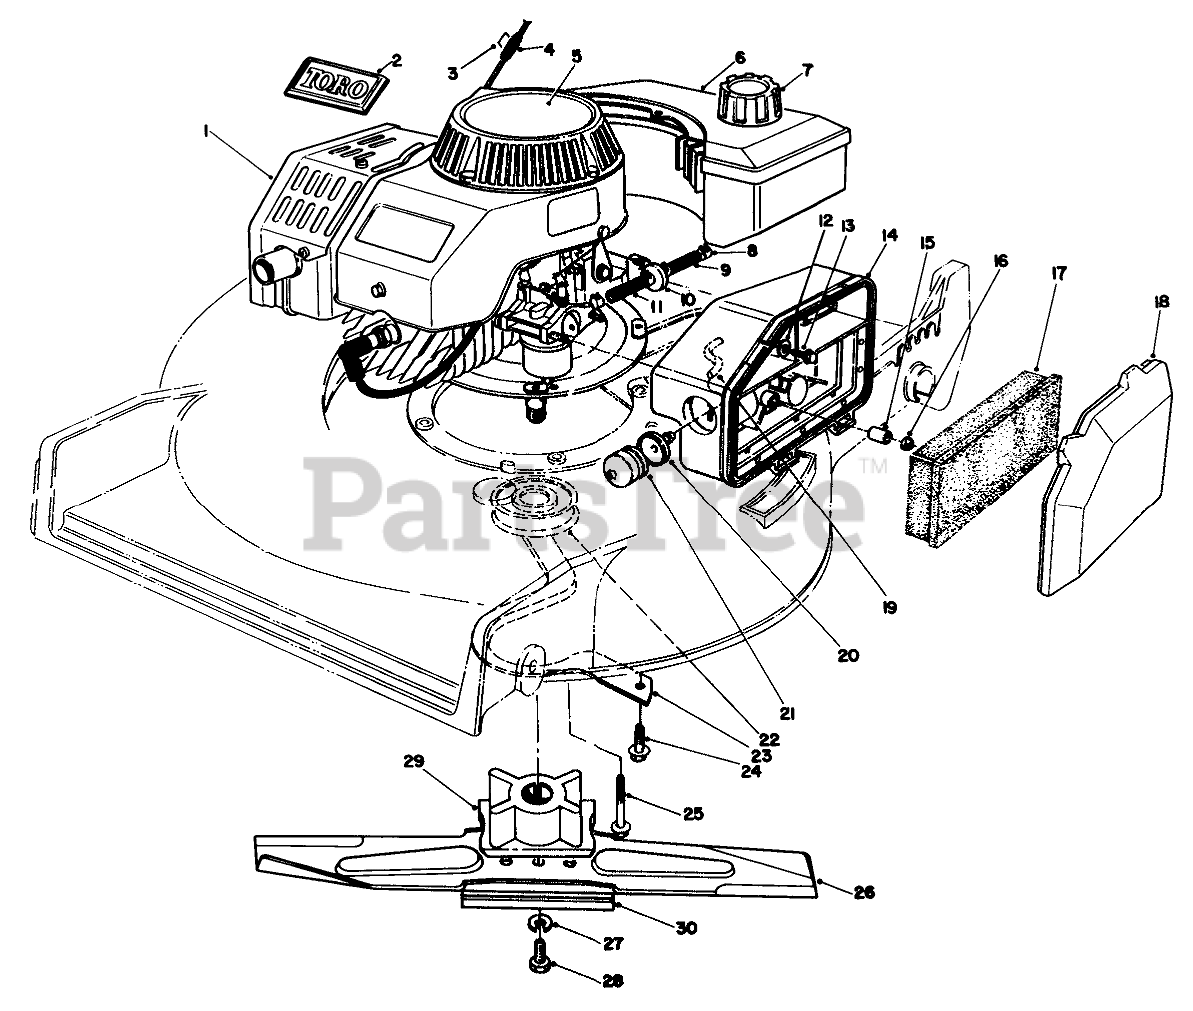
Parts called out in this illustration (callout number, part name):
1	Engine (Complete)
2	TORO LOGO PLT
3	Staple
5	DECAL - 2 CYC RECOIL
6	Gas Tank Assembly
7	GAS CAP ASM
8	CLAMP-FUEL LINE
9	HOSE-FUEL
10	FILTER-FUEL
11	HOSE-FUEL
12	WASHER-FLAT
13	SCREW-HH
14	BODY-AIR CLEANER
15	SPACER
17	ELEMENT-AIR CLEANER
18	COVER-AIR CLEANER
19	HOSE-PRIMER
20	BODY-PRIMER
21	BULB-PRIMER
22	PULLEY-DRIVE, ZONE START
23	Guide-Belt
24	SCREW-HWHTF
25	SCREW-HHF
26	Blade
27	WASHER-LOCK
28	SCREW-BLADE
29	BLADE RETAINER
30	Stiffener
